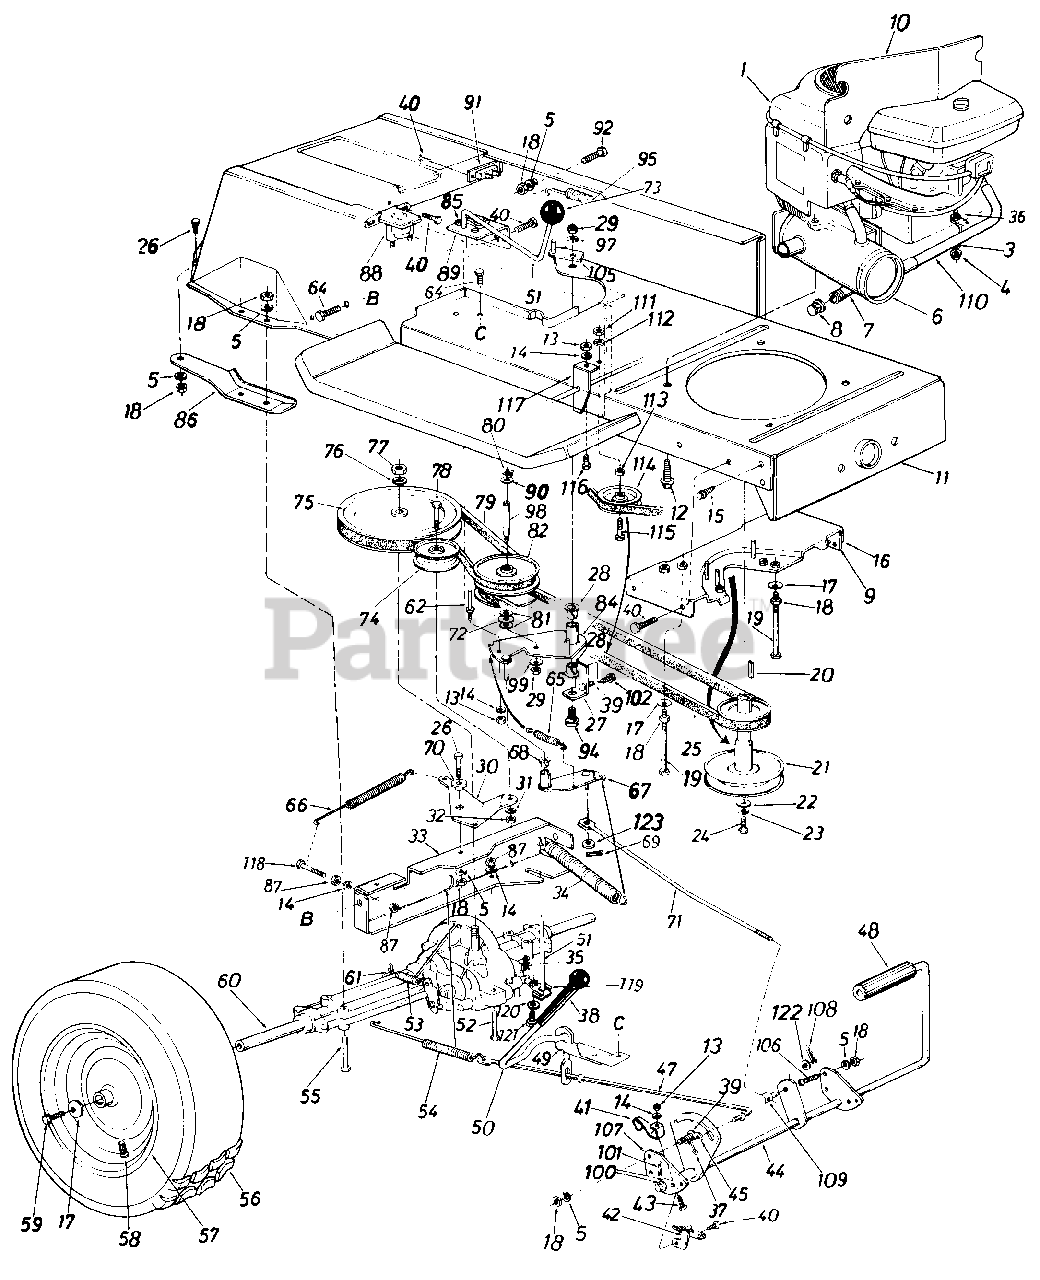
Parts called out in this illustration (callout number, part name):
1	Engine
3	Special L-Wash. 5/16" I.D.
4	Hex Nut 5/16-18 Thd.
5	L-Wash. 5/16" I.D.
6	Exhaust Muffler
7	Pipe Nipple
8	Cap Oil Drain
9	Brake Cable Brk't.
10	Heat Shield
11	Lower Frame Ass'y.
12	Hex Wash. Hd. TT-Tap Scr. 3/8-16 x 1.25" Lg.
13	Hex Nut 1/4-20 Thd.'
14	L-Wash. 1/4" I.D.'
15	Hex Wash. Hd. AB-Tap Scr. 5/16" x.75" Lg.
16	Belt Guard Brkt. Ass'y.
17	Bell-Wash. .845'1 I.D. x .88"
18	Hex Nut 5/16-18 Thd.'
19	Hex Bolt 5/16-18 x 4.00"'
20	Sq. Key 1/4" x 1/4" x 2.00"
21	Engine Pulley
22	Fl-Wash. 7/16" I.D. x 1.25"
23	L-Wash. 7/16" I.D.
24	Hex Bolt 7/16-20 x 1.50" Lg.
25	Variable-Speed Belt
26	Hex Bolt 5/16-18 x .75" Lg.'
27	Bearing Shaft Bracket Ass'y.
28	Flanged Nyliner Brg. 5/8" I.D. x .88" Lg.
29	Hex Nut 3/8-24 Thd.
30	Idler Bracket
31	L-Wash. 3/8" I.D.
32	Hex Nut 3/8-24 Thd.'
33	Transaxle Support Brkt.
34	Ext. Spring .94" O.D. x 6.7
35	Inter. Cotter Pin
36	Fl-Wash. .34" I.D. x .62" O.D. x .033
37	Cotter Pin 3/32" Dia. x .75"
39	Truss Mach. Scr. 5/16-18 x . 75" Lg .
40	Hex Wash. Hd. Self-Tap Scr. 1/4-20 x .50" Lg.
41	Switch Actuator
42	Safety Switch
43	Hex Bolt 1/4-20 x 1.0" Lg.
44	Clutch & Brake Pedal Ass'y.
45	Fl-Wash.
47	Brake Rod 20.9" Lg.
48	Foot Pad
49	Brake Lever Bracket
50	Hill Holder Brake Handle
51	Shift Lever Ass'y.
52	Hex Bolt 1/4-28 x 1.75" Lg.'
53	Ext. Spring .38" O.D. x 2.5
54	Ext. Spring .59 O.D. x 7.08"
55	Hex Bolt 5/16-18 x 2.
58	Air Valve
59	Hex Bolt 5/16-24 x .75 Lg.
60	Transaxle Complete-R.H.
61	Brake Return Spring Anchor
62	Belt Guard Pin 1/4-20 Thd.
64	Hex Wash. TT-Tap Scr. 5/16 x .62 Lg.
65	Ext. Spring
66	Ext. Spring .62 O.D. x 6.12
67	Variable Speed Torque Brkt. Ass'y.
68	Flanged Bearing
69	Cotter Pin 3/32 Dia.
70	Shoulder Spacer .500 Dia. x.27 Lg.
71	Speed Control Link
72	Truss Bearing .56 Dia. x 1 .25
73	Ball Knob
74	Fl-ldler Pulley 3.25 x .75
75	1/2" "V"-Pulley 8.0 O.D. x.501" I.D.
76	L-Wash. 1/2" I.D.
77	Hex Jam Nut 1/2-20 Thd.
78	Hex Bolt 3/8-24 x .75 Lg.
79	Variable Speed Belt
80	Snap Ring .56 Dia.
82	Variable Speed Pulley Ass'y. 5 O.D.
84	Variable Speed Brkt. Ass'y.
85	Comp. Spring Clip
86	Transaxle Support Brkt.-R.H.
87	Hex Nut 1/4-28 Thd.
88	Solenoid
89	Shift Lever Bracket
90	Teflon Washer
91	Circuit Breaker
92	Hex Bolt 5/16-18 x 1.50"
94	Shld. Bolt 3/8-24 x 3.12 Lg.
95	Ext. Spring .99" O.D. x 11.0"
97	Bell-Wash. .38 I.D. x .88
98	Shaft .56 Dia. x 3.875 Lg.
99	Bell-Wash. .39 I.D. x 1.12
100	Fl-Wash.
101	Cotter Pin 3/32" Dia. x .75"
102	Hex Wash. Hd. Scr. 5/16-18 x.62" Lg.
105	Belt Guard
106	Hex Bolt 5/16-18 x .75" Lg.
107	Pedal Bracket
108	Cotter Pin 3/32 x .75"
109	Ferrule
110	Inlet Tube Ass'y.
111	Hex Nut 3/8"-16 Thd.
112	L-Wash. 3/8" I.D.
113	Fl-Wash. .390" I.D. x 1.12"
114	Fl-ldler w/Flanges 2.750
115	Hex Bolt 3/8-16 x 2.00" Lg.
116	Hex Bolt 1/4-20 x .62" Lg.
117	Spring Hanger Bracket
118	Hex Bolt 1/4-28 x 1.25" Lg.
119	Shift Lever Link Ass'y.
120	Bell-Wash. .265 I.D. x .75 O.D.
121	Hex Bolt 1/4-28 x .62" Lg.
122	Fl-Wash. .385" I.D. x .62" O.D.
123	Fl-Wash. .34" I.D. x .68" O.D.
